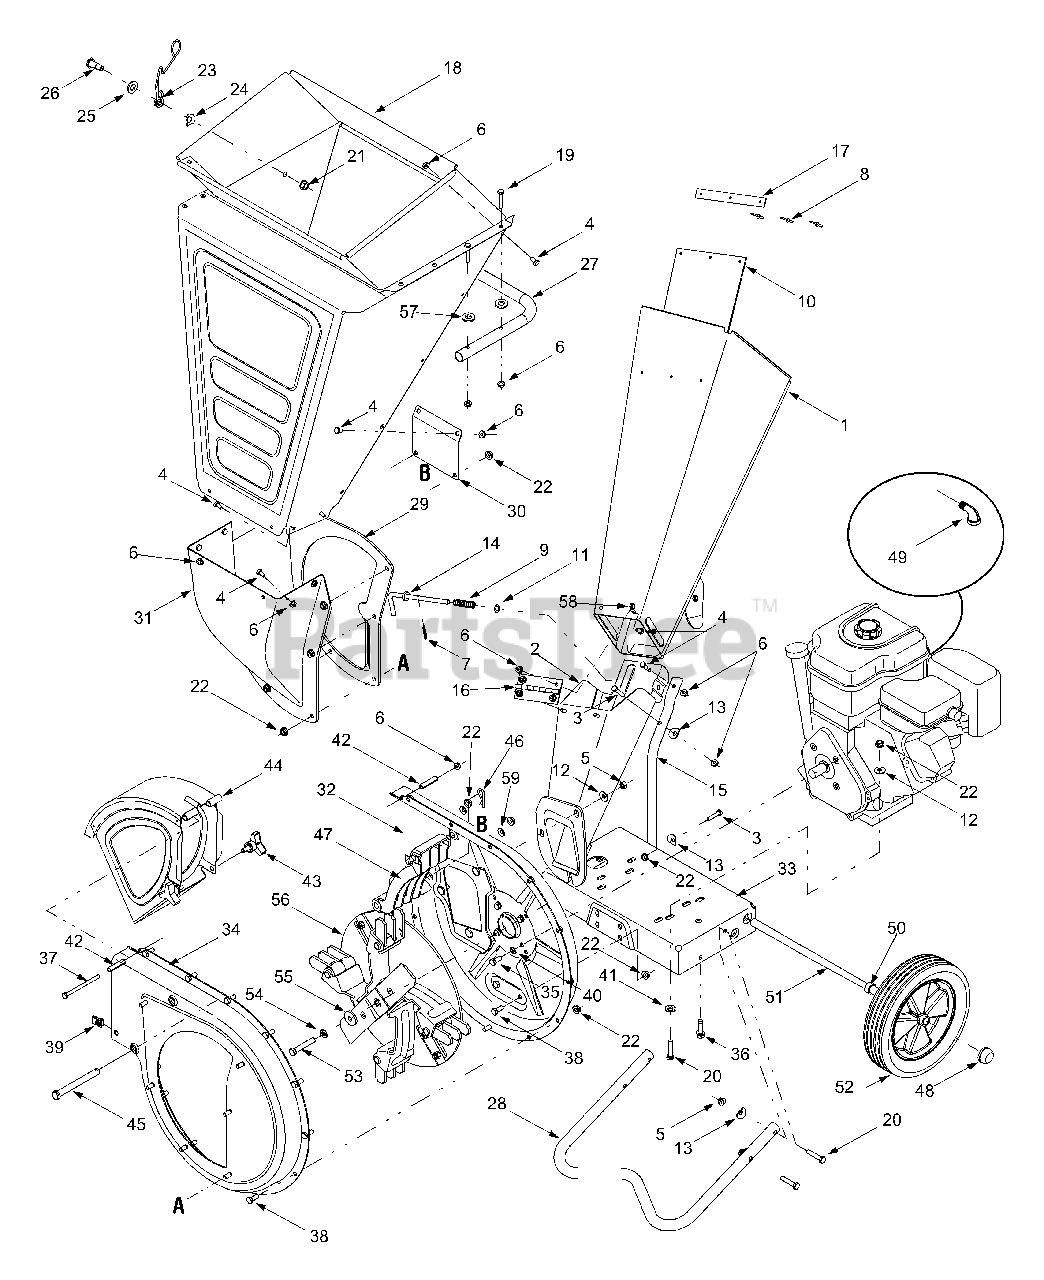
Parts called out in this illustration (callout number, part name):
3	Hex Cap Screw, 1/4-20 x 1.25
4	Hex Cap Screw, 1/4-20 x.5
5	Hex Nut, 5/16-18
6	Hex Lock Nut 1/4-20
7	Cotter Pin
8	Pop Rivet
9	Compression Spring,.531 x 1.75
10	Chute Flap
11	Flat Washer
12	Bell Washer.340 ID x.872 OD
13	Washer,.320 ID x.93 OD
14	Lock Rod
16	Chipper Chute Hinge
17	Chute Flap Strip
20	Hex Cap Screw, 5/16-18 x 1.50
21	Flange Lock Nut, 3/8-16
22	Flange Lock Nut, 5/16-18
23	Torsion Spring
24	Spring Washer,.50 x 1.0 x.022
25	Flat Washer,.50 x 1.0 x.0125
26	Shoulder Screw, 3/8-16,.50 x.685
35	Hex Cap Screw, 5/16-24 x.75
36	Hex Sems Screw, 3/8-16 x 1.25
37	Hex Cap Screw, 1/4-20 x 3.75
38	Hex Cap Screw, 5/16-18 x.75
39	U-Nut, 5/16-18
40	Lock Washer, 5/16
41	Special Lock Washer, 5/16
42	Hinge Spacer,.265 x.380 x 1.66
43	Knob, 5/16-18
45	Clevis Pin,.50 x 4.62
46	Internal Cotter Pin
47	Shredder Screen
48	Push Cap, 5/8
49	Oil Drain Tube
50	Spacer,.64 x.88 x.38
51	Axle, 21.21"
52	Wheel, 10 x 2.5
53	Hex Cap Screw, 3/8-24 x 2.25
54	Lock Washer, 3/8
55	Flat Washer,.406 x 1.25
56	Impeller Assembly
57	Flat Washer,.28 x.74 x.063
58	Push Nut,.25ID x.50OD
59	Speed Nut,.3125ID
